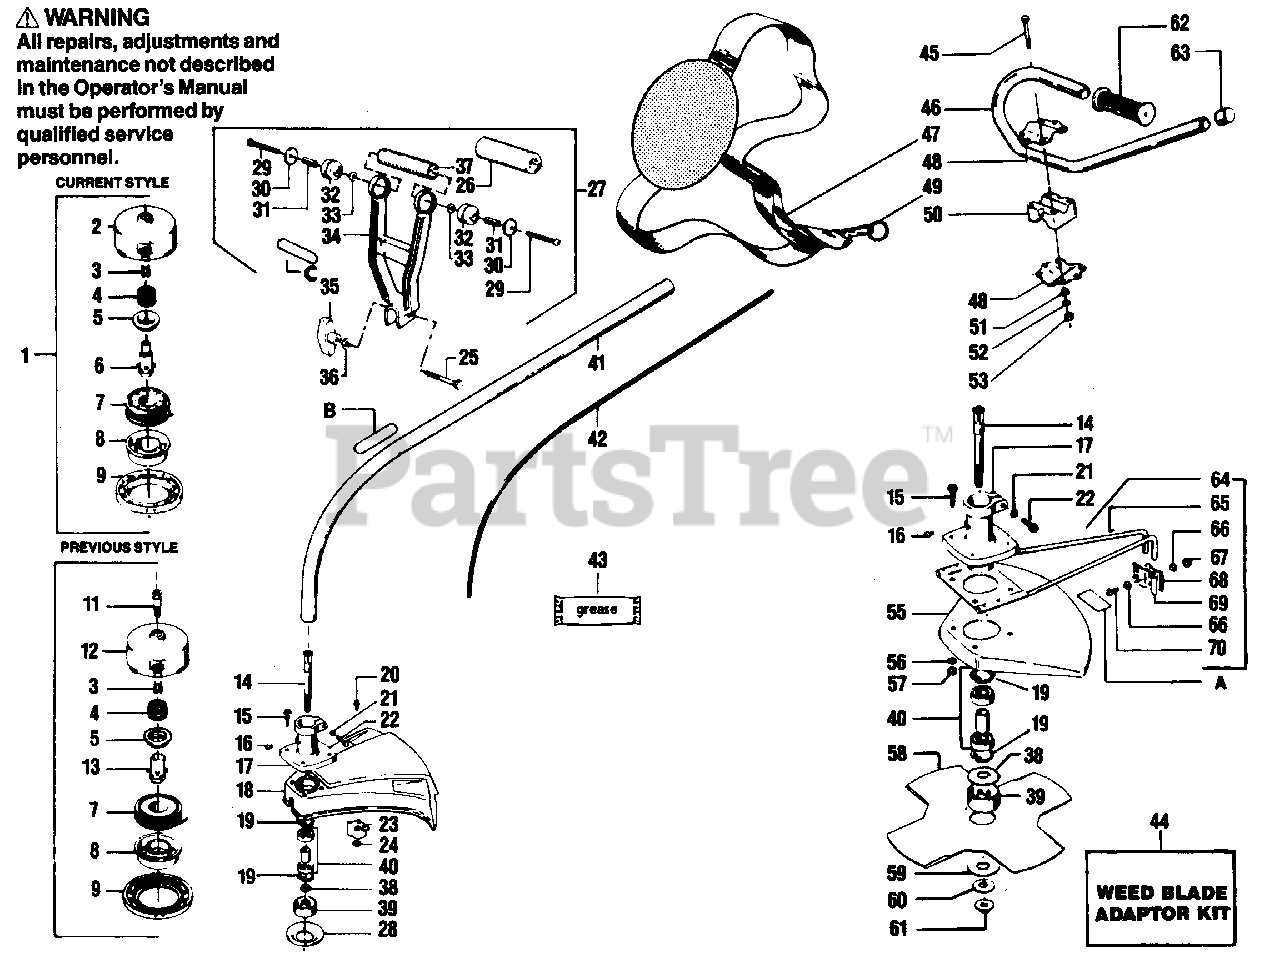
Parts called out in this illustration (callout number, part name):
1	Cutting Head Ass'y - Current Style (Inc.2,9)
2	Hub w/Line Saver - Current Style
3	Line Saver
4	Spring
5	Adapator-Spring
6	Drive Gear - Current Style
7	Spool w/Line
8	Release Button
11	Bolt - Drive Adaptor - Previous Style
12	Hub w/Line Saver - Previous Style
13	Drive Gear - Previous Style
14	Arbor Shaft
15	Screw
15	Model XR-80
15	Model XR-75,XR-85
16	Screw - #10 - 16 x 1/4" - Self Tapping
17	Bearing Housing Ass'y (Inc. #14, 19, 21, 22, 38 & 39)
18	Shield Assembly - 18" (Inc. #20, 23 & 24) Model XR-80
19	Retainer - Bearing
20	Screw - #10 - 24 x 5/8" - Hex Hd. - Line Limter - Model XR-80
21	Washer - #1/4 Int. Tooth Lock
22	Screw - Pinch Clamp - #1/4 - 20 x 1" Model XR-80 only (Inc. #23-37)
23	Line Limiter
24	Nut - #10 - 24 - Locking
25	Hex Bolt
26	Cushion - Handle Center Section
27	Handle - Antivibe Assembly (Inc. #29-30)
29	Screw - Pan Hd. - #12 - 11 x 2"
30	Cup Isolator
31	Spacer - Isolator
32	Isolator - Vibration
33	Washer - #1/4 Flat
34	Handle - Antivibe
35	Knob - #1/4 - 20
36	Washer - #1/4 Flat
37	Center Section - Handle
38	Washer - #3/8 - Dust Cup
39	Dust Cup
40	Bearings & Spacer Kit
41	Drive Shaft Housing
42	Flexible Drive Shaft
43	Flex Shaft Lube
44	Weed Blade Adaptor Kit - Model XR-80 (Inc. #45-70)
45	Bolt - #1/4 - 20 x 2" Hex
46	Barrier Handlebar
47	Shoulder Strap
48	Clamp - Handleabr
49	Key Ring - Shoulder strap
50	Block - Handlebar
51	Washer - #1/4 Flat
52	Washer - #1/4 Lock
53	Nut - #1/4 - 20 Hex
55	Shield - Aluminum
56	Washer - #1/4 Flat
57	Nut - Deflector to Brg. Hsg. (#1/4 - 20)
58	Blade - 4 Tooth Weed
59	Washer - #3/8 Flat
60	Washer - #1-1/8 - 3/8 Bevel
61	Flange Nut - #3/8 - 24
62	Grip - Handlebar
63	End Cap - Handlebar
64	Line Limiter Ass'y. (Inc. #65-70)
65	Line Limiter Bracket
66	Washer
67	Nut - #10 - 24 Locking
68	Clamp - Line Limiter Front
69	Clamp - Line Limiter Rear (Inc. Blade)
70	Screw - #10 - 24 x 3/8"
A	Decal - Blade Rotation Waming
B	Decal - Safety Label
C	Decal - Antivibe (Warning)
